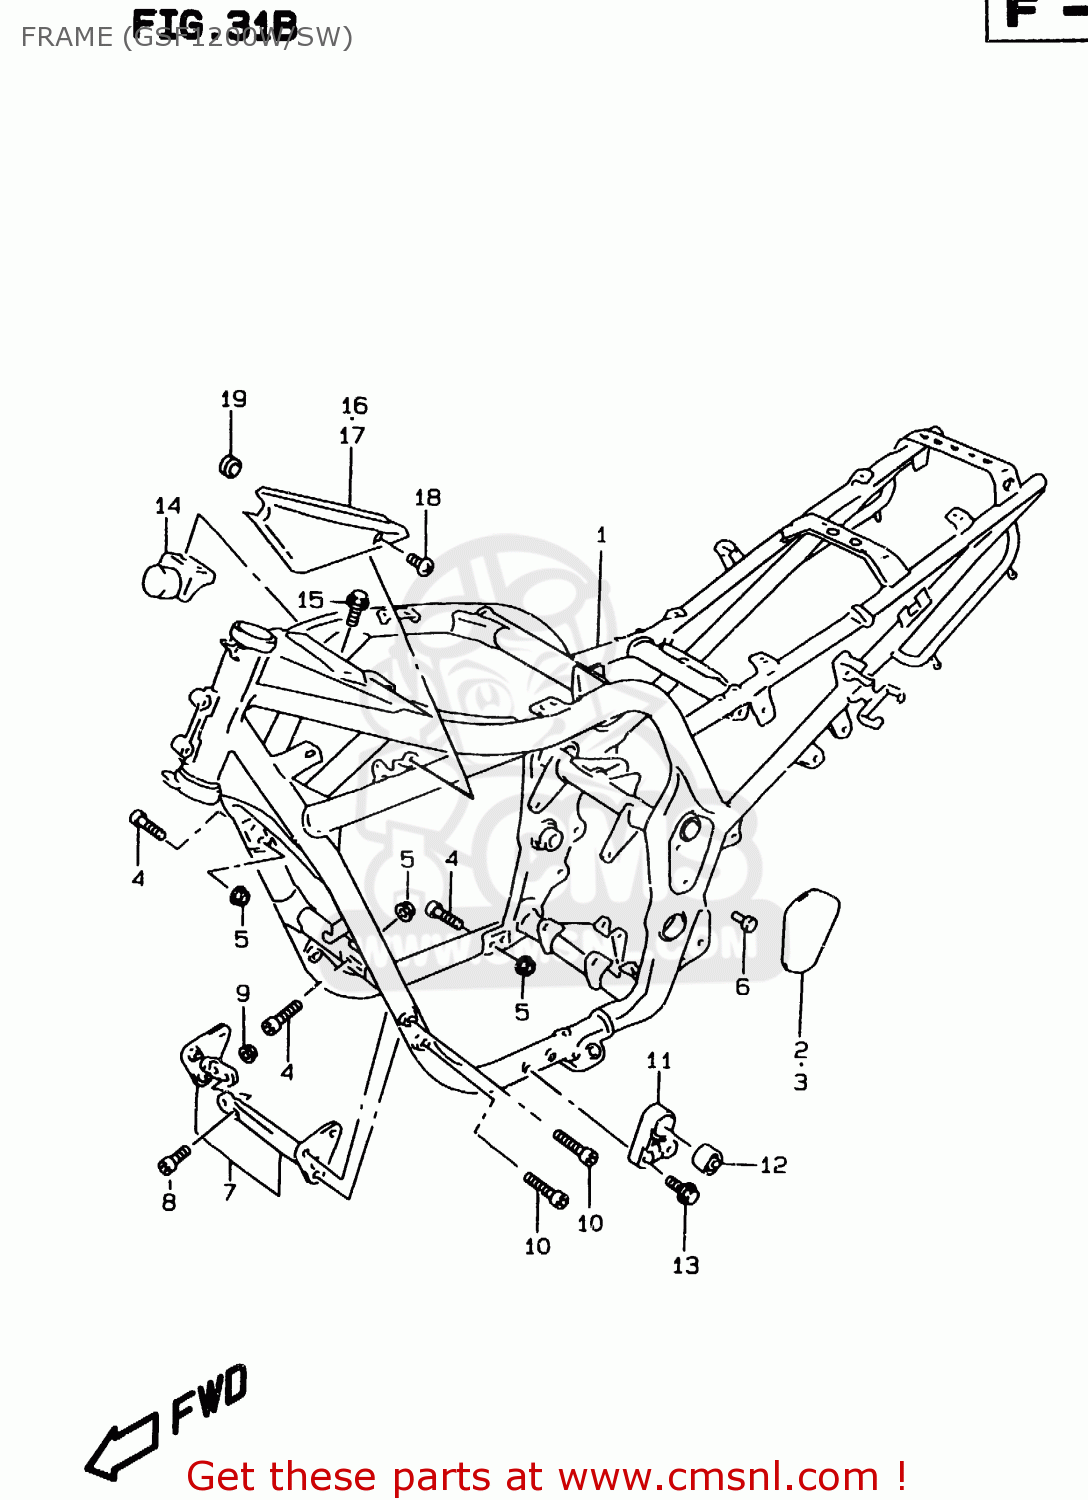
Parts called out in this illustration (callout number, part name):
1	FRAME COMP
2	COVER,FRAME BODY,R
3	COVER,FRAME BODY,L
4	BOLT(10X33)
5	NUT
6	CLIP
7	PLATE ASSEMBLY,ENGINE MOUNT
8	BOLT
9	NUT
10	BOLT
11	BRACKET,ENGINE MOUNTING NO.2
12	BUSH,ENG MOUNTING NO.2
13	BOLT
14	DAMPER COMP,FRAME
15	BOLT
16	COVER,FRAME HEAD,R
17	COVER,FRAME HEAD,L
18	SCREW(5X12)
19	CUSHION
